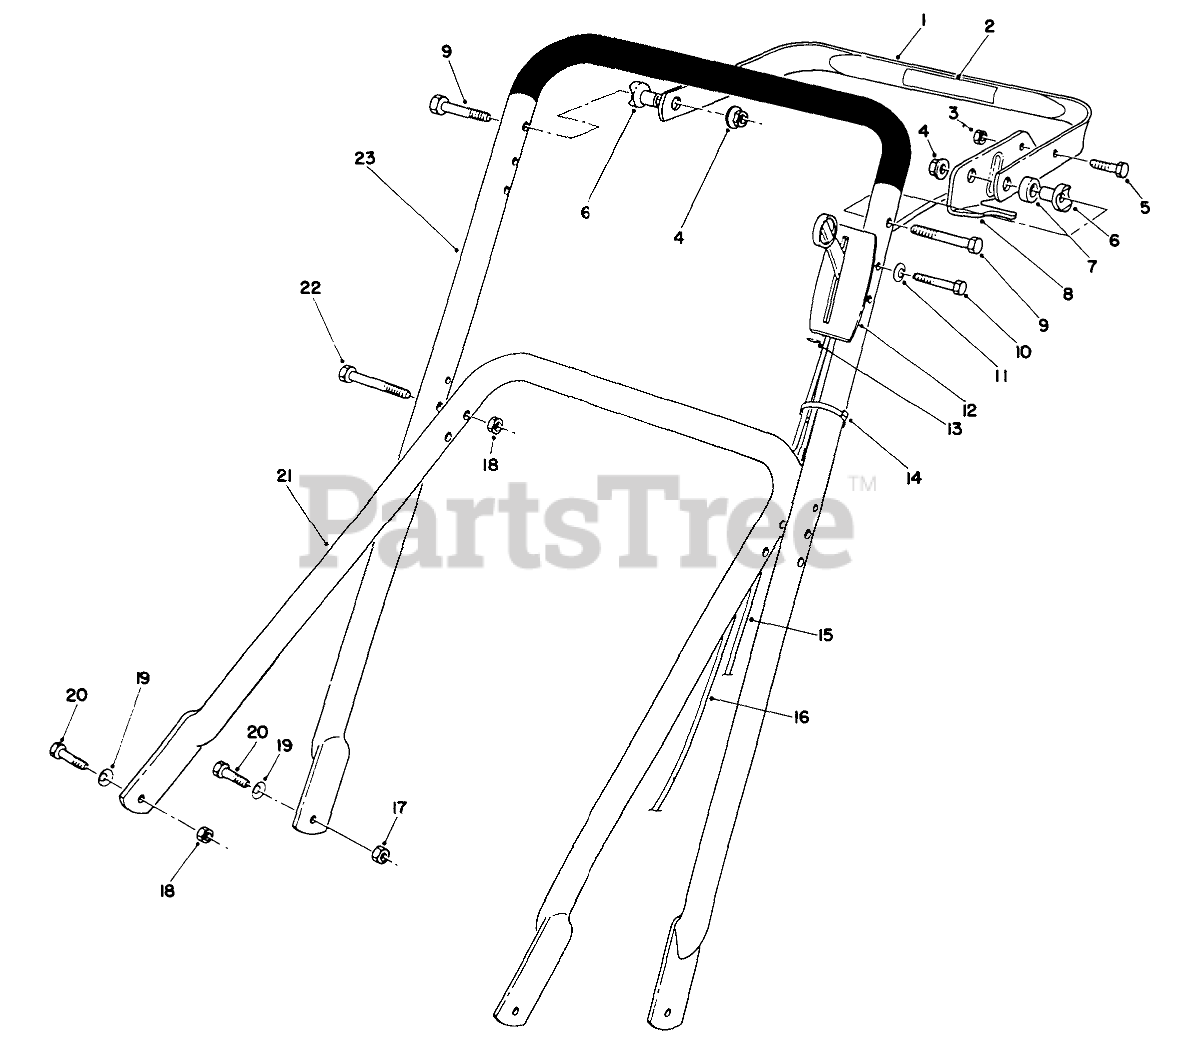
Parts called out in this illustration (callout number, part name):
1	Bar-Control
2	DECAL - INT'L TRACTION
3	NUT-LOCK, NI
4	NUT-LOCK, NI
5	SCREW-HH
6	SPACER-SUPPORT
7	SPACER-NYLON
8	LEVER-CONTROL
9	SCREW-HH
10	SCREW-HH
11	WASHER
12	THROTTLE CONTROL BRKT
13	E-RING
14	TIE-CABLE
15	CABLE-TRACTION
16	CABLE-THROTTLE
17	NUT-LOCK, NI
18	NUT-LOCK, NI
19	WASHER-BELLEVILLE
20	SCREW-HH
21	Handle-Lower
22	SCREW-HH
23	Handle
